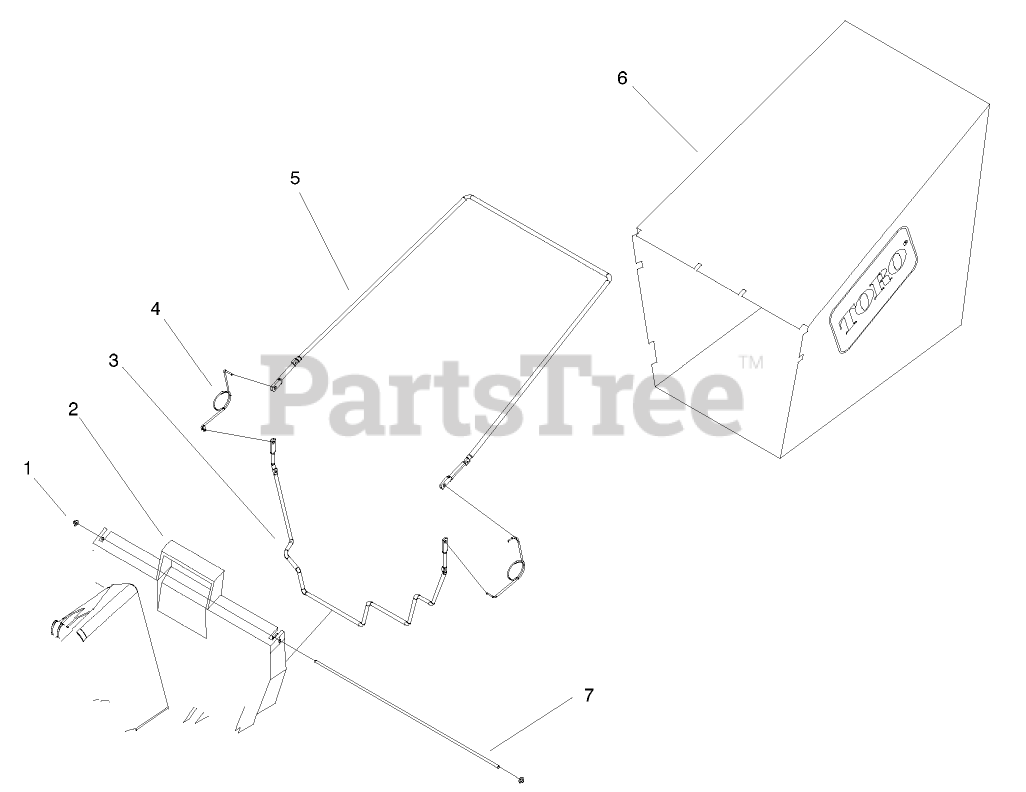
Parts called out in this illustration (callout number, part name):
1	NUT-PUSH
2	DOOR-BAG
3	FRAME-BAG, LOWER
4	SPRING
5	FRAME-BAG, UPPER
6	BAG-GRASS
7	HINGE-DOOR, BAG
